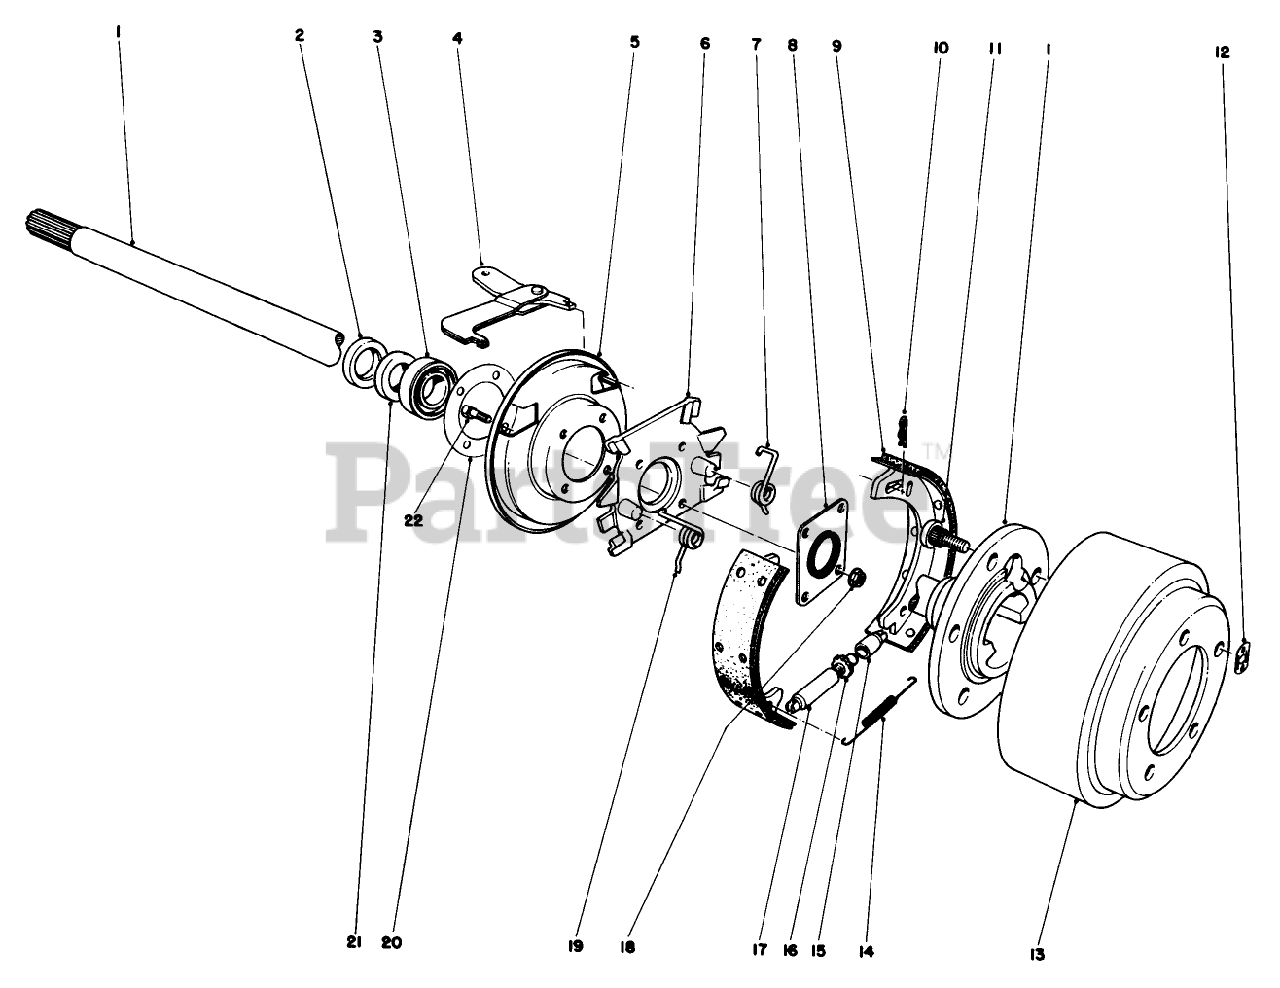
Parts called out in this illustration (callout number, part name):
1	SHAFT-AXLE, FLANGED
2	Oil Seal
3	BEARING ASM
4	STRUT AND LEVER ASM
5	SHIELD-DUST
6	SPIDER-TORQUE
7	SPRING-RETURN, RH
8	SEAL-GREASE
9	Assy.-Shoe & Lining
10	RETAINER-LEVER, BRAKE
11	STUD-DRIVE
12	CLIP-RETAINING
13	DRUM-BRAKE
14	SPRING-SCREW, ADJUSTING
15	SOCKET-SCREW, ADJUSTING
16	SCREW-ADJUSTING
17	NUT-PIVOT
18	Locknut
19	SPRING-RETURN, LH
20	Gasket Wheel Baaring
21	RING-RETAINING, WHEEL BEARING
22	Screw
